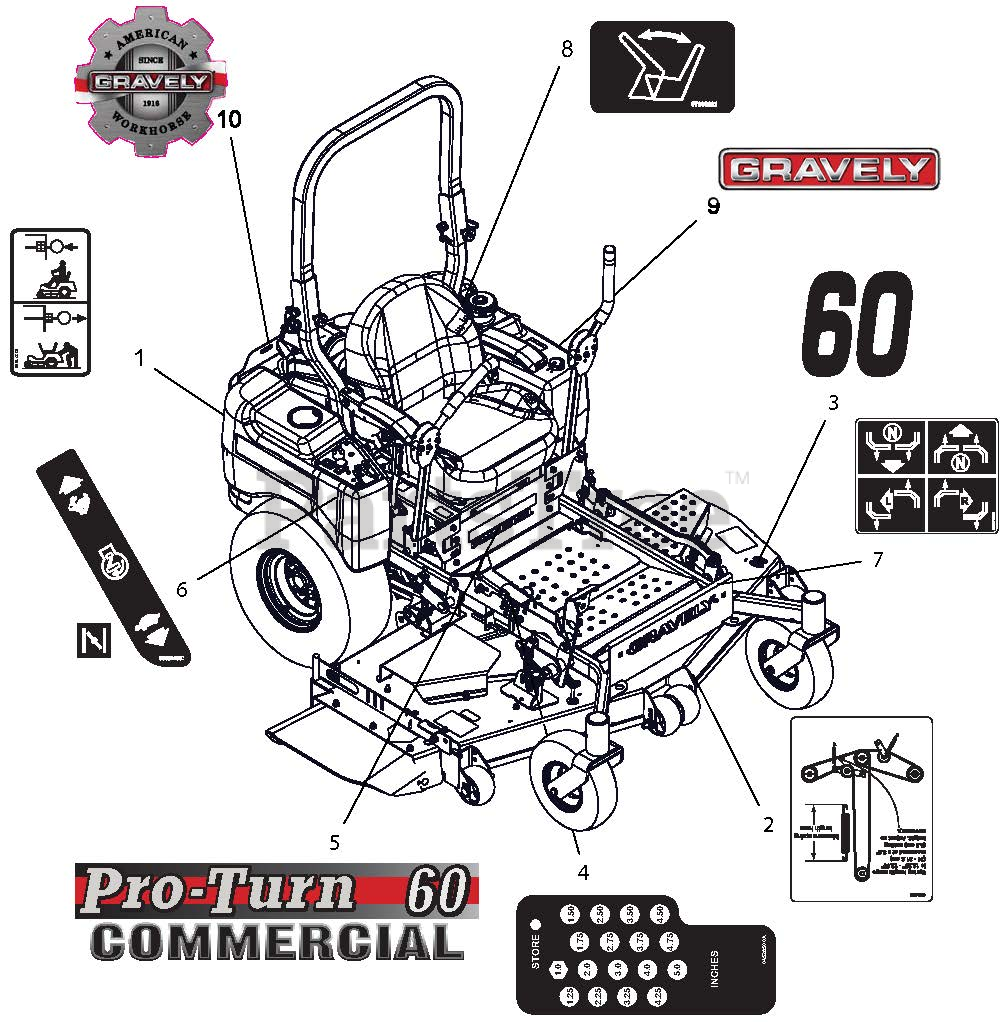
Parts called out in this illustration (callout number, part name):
1	DECAL, TRANSMISSION DISCONNECT
2	DECAL, BELT ROUTING
3	DECAL, 60"
4	DECAL, HEIGHT OF CUT
5	DECAL, 60" PRO-TURN
6	DECAL, SPEED CONTROL
7	DECAL, INSTRUCTIONAL - STEERING
8	DECAL, SEAT RELEASE
9	DECAL, FUEL TANK-GRAVELY
10	DECAL, GRAVELY HERITAGE-LARGE
